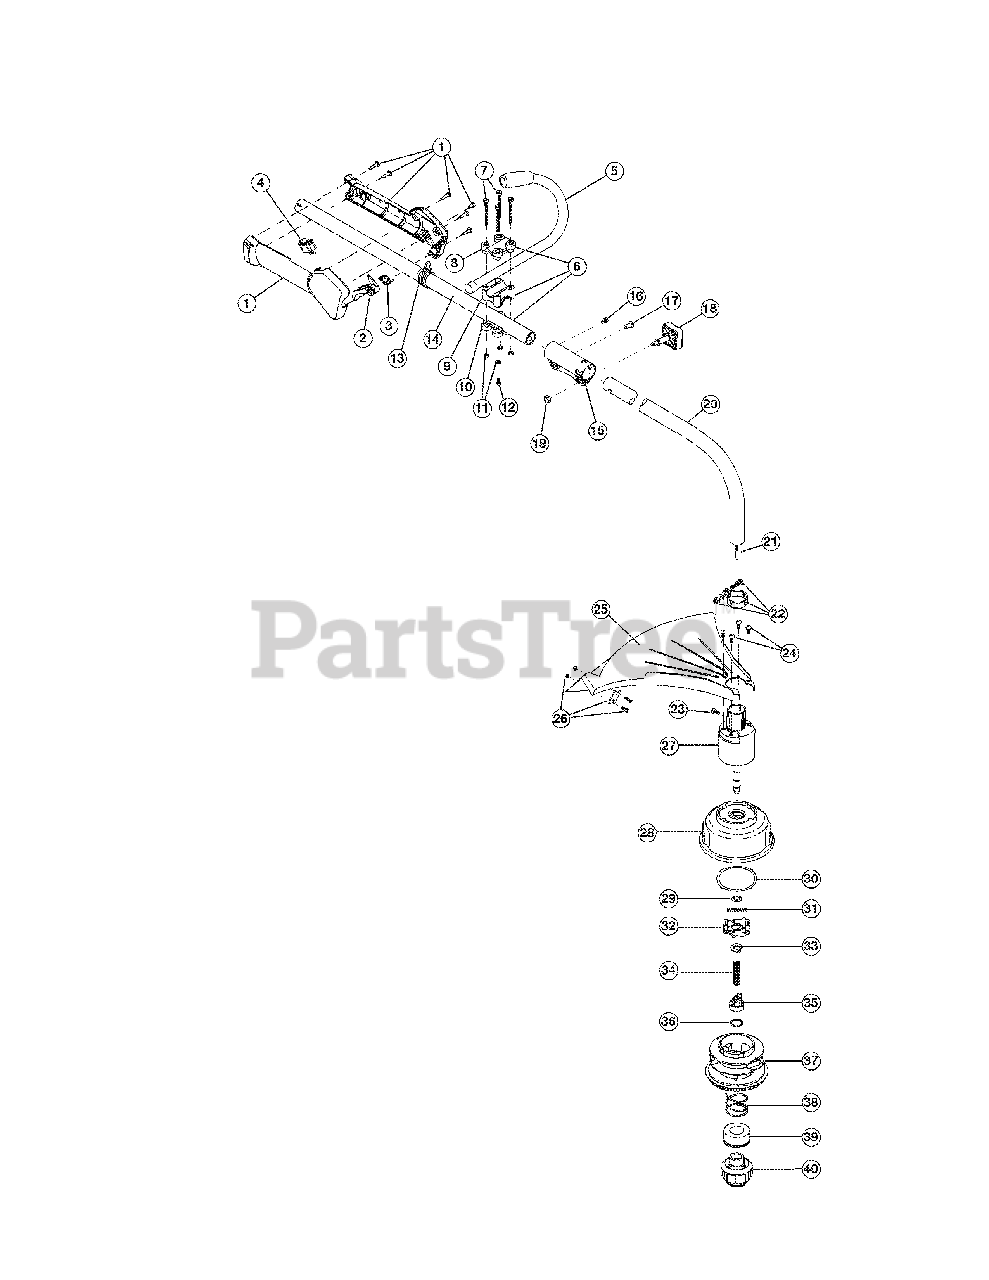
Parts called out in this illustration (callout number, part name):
1	Throttle Housing Assembly (includes 2-4)
2	Throttle Trigger
3	Throttle Trigger Spring
4	Switch Assembly
5	J-Handle Assembly
6	Handle Bracket Assembly (includes 7-12)
8	Upper Handle Clamp
9	Middle Handle Clamp
10	Lower Handle Clamp
12	Anti-Rotation Screw
13	Harness Clip
14	Upper Drive Shaft Housing Assembly
15	Split Boom Coupler (includes 16-19)
18	Adjustment Knob (includes 19)
19	Knob Retaining Nut
20	Lower Drive Shaft Housing Assembly
21	Lower Flexible Drive Shaft
22	Lower Clamp Assembly
23	Anti-Rotation Screw
24	Shield Mounting Hardware
25	Shield Assembly (includes 26)
26	Blade Assembly
27	Bushing Housing Assembly
28	Outer Spool Assembly (includes 29)
29	Retaining Ring
30	Thrust Washer
31	Small Spring
32	Slider
37	Inner Reel
38	Large Spring
40	Bump Head Knob Assembly (includes 38 & 39)
